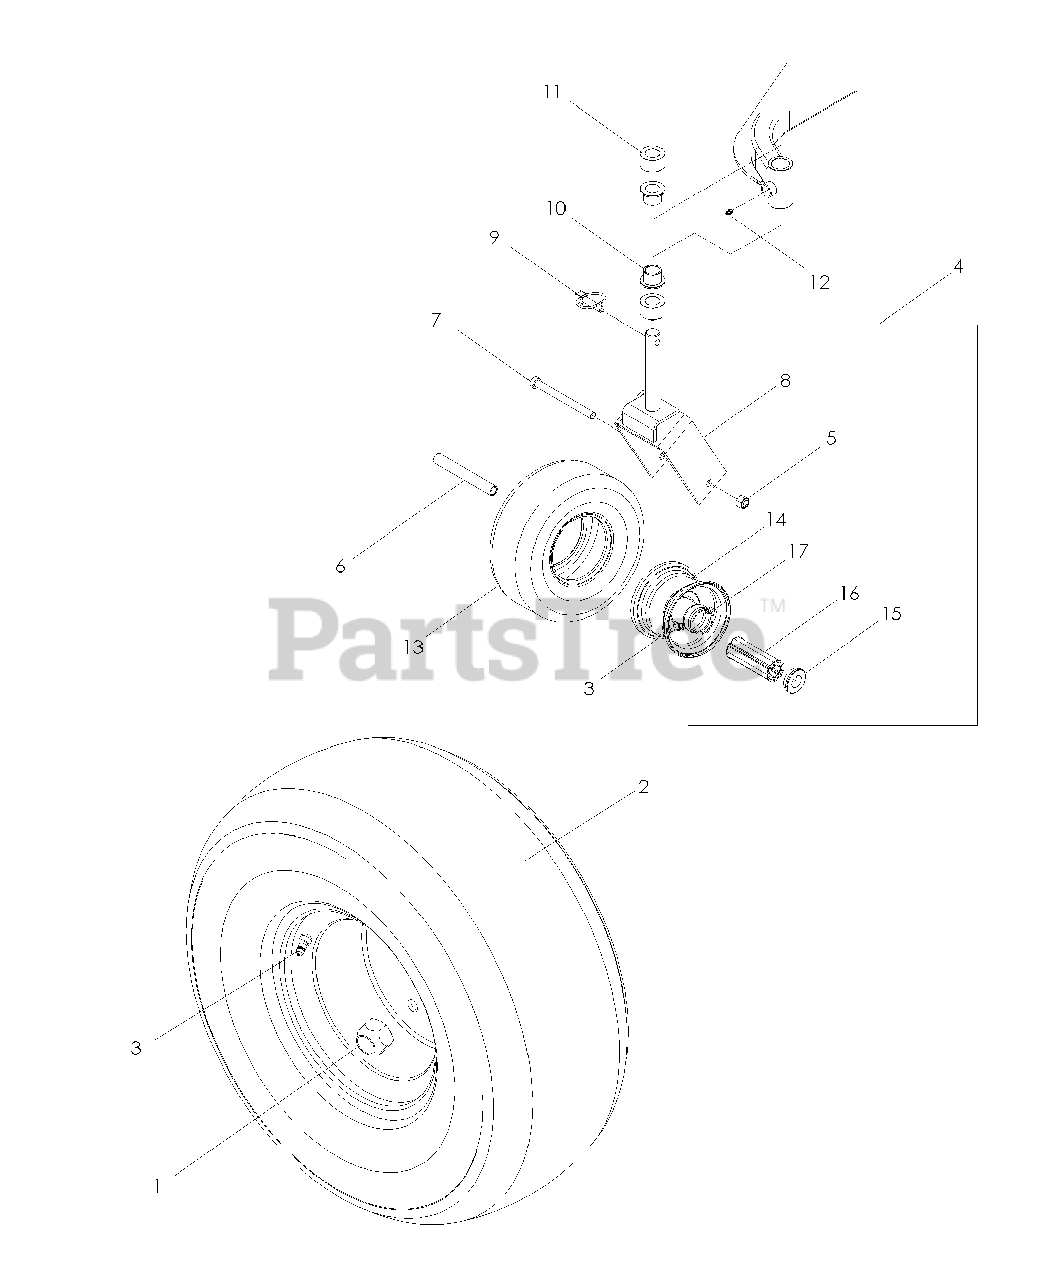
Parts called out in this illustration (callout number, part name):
2	WHEEL ASSM, REAR
3	VALVE STEM
4	CASTER ASSEMBLY
5	NUT 1/2-13 HEX NYLOC
7	HCS 1/2-13 x 5 1/2
8	FORK, CASTER
9	LYNCH PIN, 7/16
10	BUSHING, CASTER
12	ZERK
13	TIRE
15	BEARING, FLANGE
16	BEARING, ROLLER, 3 1/4
17	ZERK
